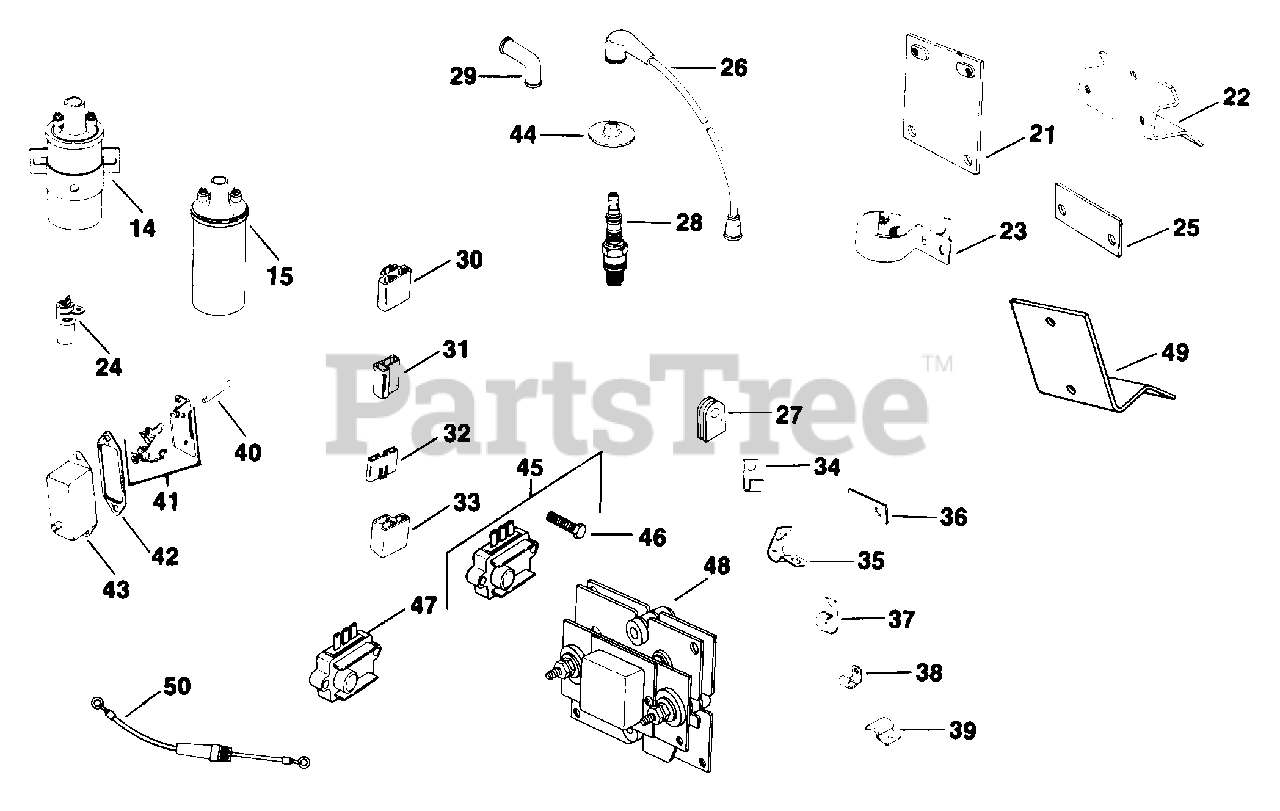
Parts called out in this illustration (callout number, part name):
14	COIL, IGNITION USE 41 519 21-S
24	CONDENSER
28	SPARK PLUG USE 25 132 10-S
42	GASKET, POINT COVER
